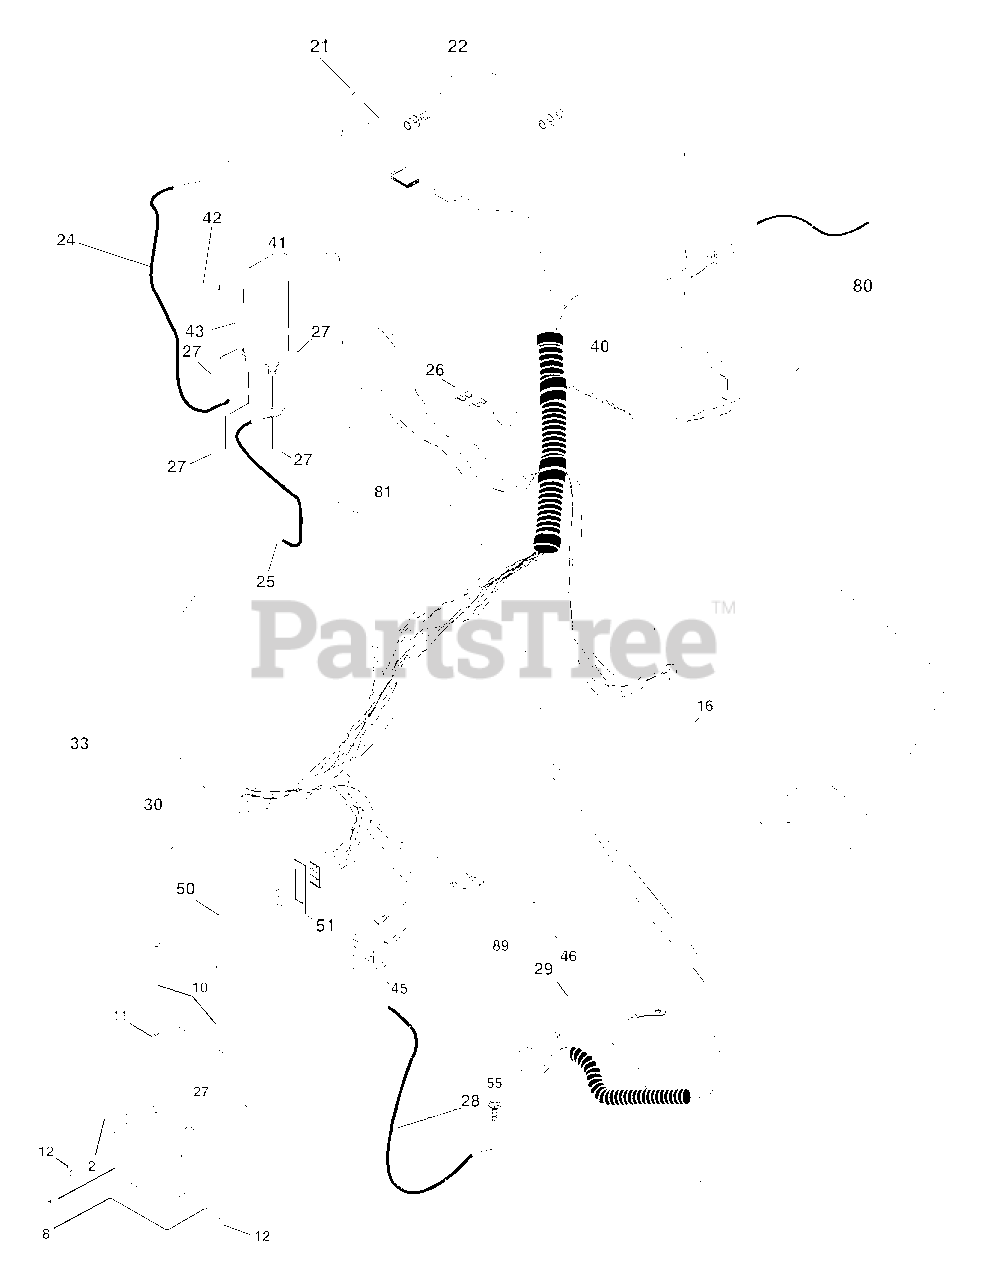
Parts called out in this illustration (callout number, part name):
1	Battery 12 Volt 25 AMP
2	Bolt Hex Hd 1/4-20unc X 3/4
8	Tray Battery
10	Bolt Brt Frt 1/4-20 x 75 Ainc
11	Holddown Battery Front Mount
12	Nut Push Nylon 1/4" Battery Frt
16	Switch Interlock Push-In
21	Harness Asm Light W/4152j
22	Bulb Light #1156
24	Cable Battery 6 Ga 22" red w/16 wire
25	Cable Battery 6 Ga 11" red
27	Nut Keps Hex 1/4-20 Unc
28	Cable Ground 6 Ga 21" black
29	Switch Plunger Nc Gray
30	Switch Ign
33	Key Ign Molded Generic
40	Harness Ign.
41	Bolt Blk Fin Hex 1/4 - 20 x 1/2
42	Cover Terminal Red
43	Solenoid
45	Ammeter Rectangular 15 Amp
46	Meter Hour
50	Switch PTO
51	Ring Retainer TTO
55	Screw Thdrol 5/16-18 x 1-1/2 Tyt
80	Harness Clutch Evx
81	Relay Asm.
89	Bracket Snap-In Hourmeter
